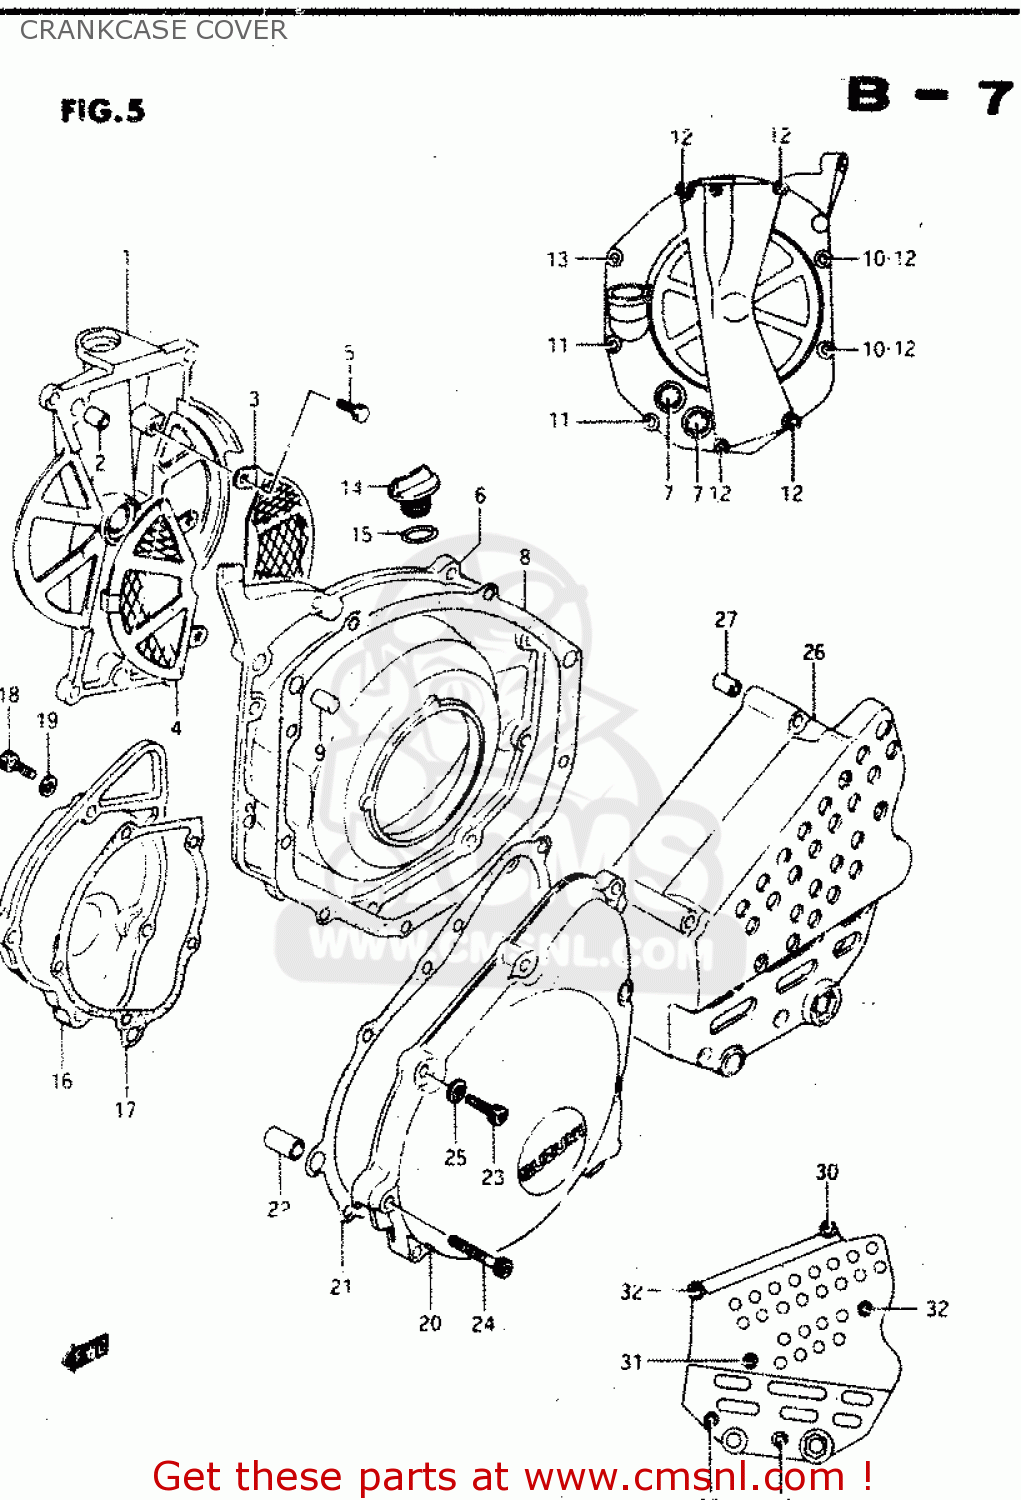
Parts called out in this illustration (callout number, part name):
1	COVER,CLUTCH,OUTER
2	PIN
3	PLATE,OUTER COVER,LEFT
4	PLATE,CLUTCH OUTER COVER
5	BOLT 5X16
6	COVER,CLUTCH
7	LENS,OIL LEVEL CHECK
8	GASKET,CLUTCH COVER
9	PIN (9X18)
10	GASKET(5.8X13X1.2) (NAS)
11	BOLT
12	BOLT
13	BOLT 6X35
14	PLUG
15	O RING(D:3.1,ID:16.8)
16	COVER,SIGNAL GENERATOR
17	GASKET,SIGNAL GENERATOR COVER (NAS)
18	BOLT
19	GASKET(5.8X13X1.2) (NAS)
20	COVER,STARTER GEAR
21	GASKET,STARTER GEAR COVER (MCA)
22	PIN (11X20)(SUS)
23	BOLT
24	BOLT
25	GASKET(5.8X13X1.2) (NAS)
26	COVER,SPROCKET
27	PIN
28	BOLT
29	BOLT
30	BOLT
31	BOLT
32	BOLT
